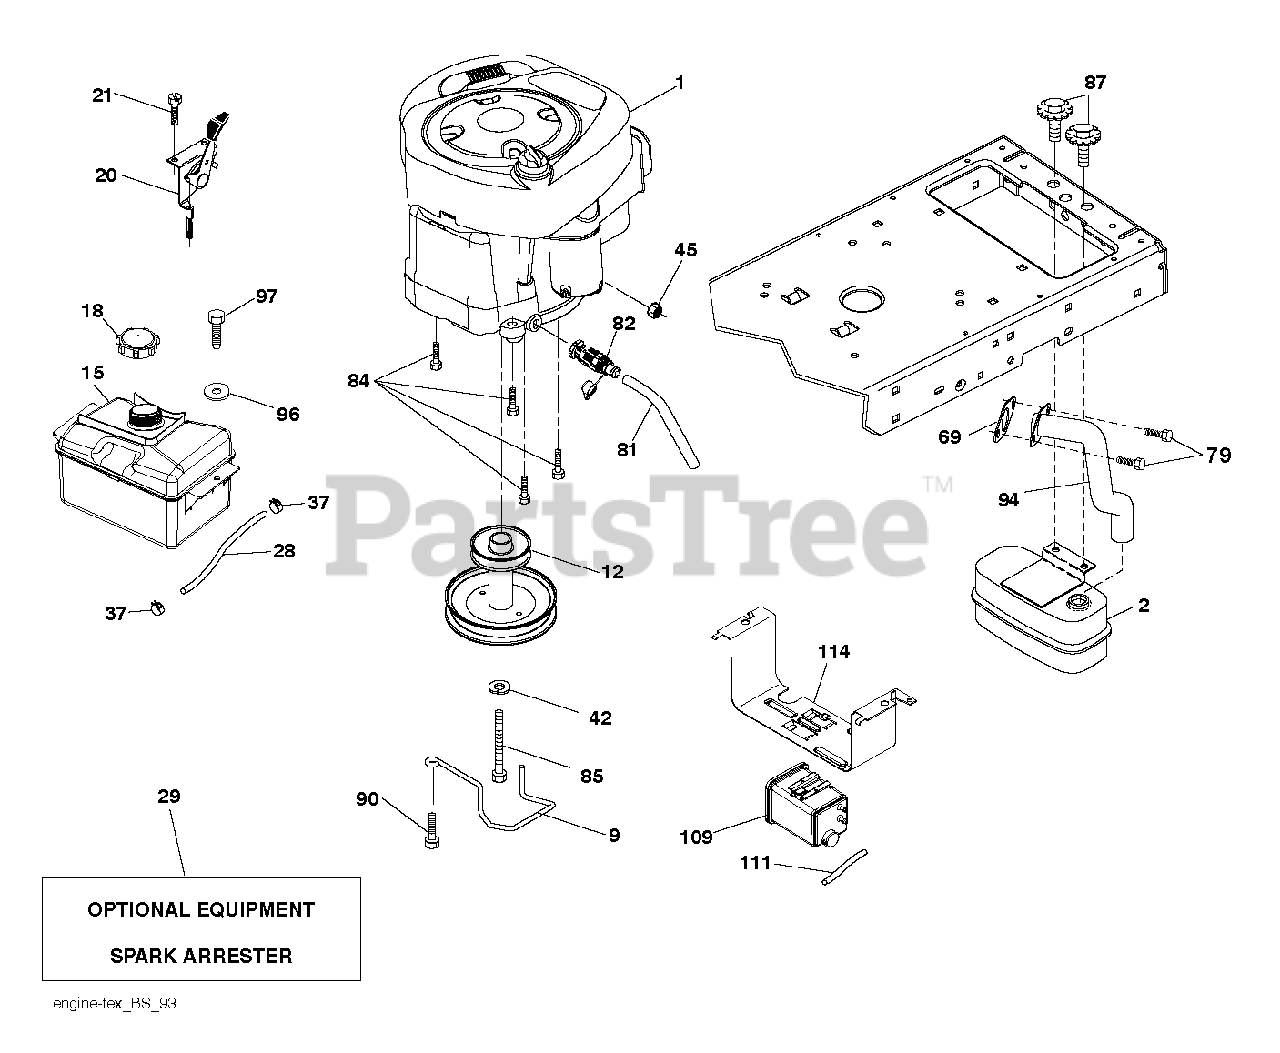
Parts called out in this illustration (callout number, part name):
2	MUFFLER.SINGLE.LRG.BRIGGS.KOHL
9	KEEPER.BELT.ENGINE.3.25
12	PULLEY ENGINE
15	TANK ASM.FRT.CRB.1.5GA.E10.SVC
18	CAP ASM.FUEL.2.25"FRT.CARB
21	SCREW.#10 X 0.750.BOS (2 2)
28	LINE.FUEL.20"FRONT.EMI
29	SPARK ARRESTOR KIT
37	HOSE CLAMP
42	LOCKWASHER
45	NUT
79	SCREW.SOCKET HD.5/16-1
81	TUBE, DRAIN OIL ASM.
82	VALUE.OIL.DRAIN
84	SCREW.3/8-16
85	BOLT HEX 7/16-20X4-1/4"
87	BOLT, 5/16-18 X 1 3/4
90	SCREW 3/8-16X1
94	Exhaust Tube, B&S 28/31
97	SCREW HEXWSHR 1/4-20X3/4
109	CANNISTER, CARBON
111	RP PURGE LINE
